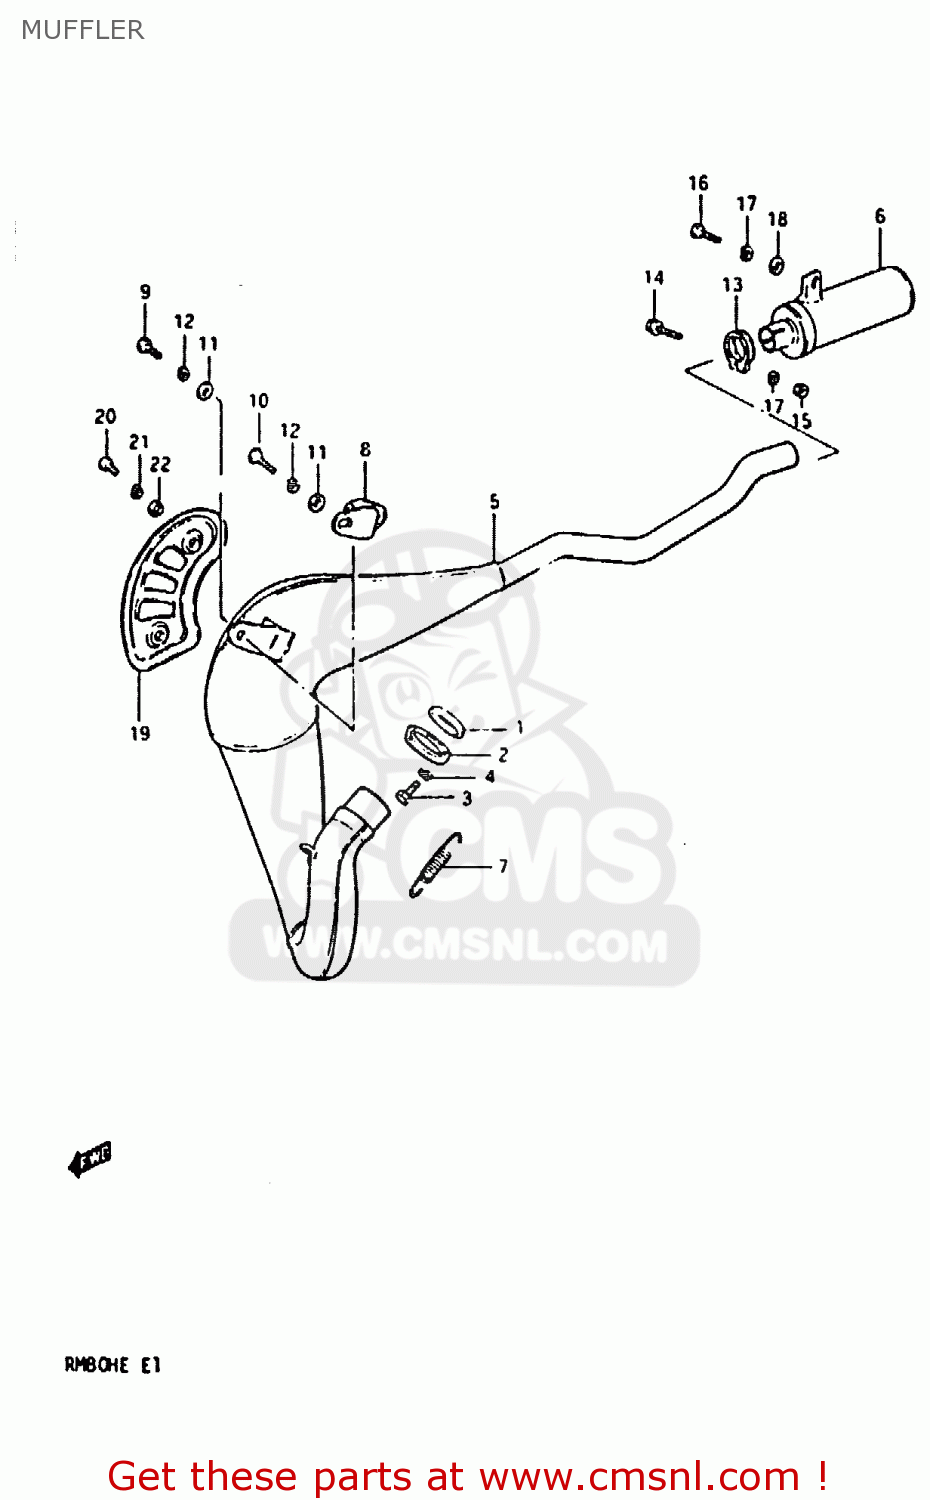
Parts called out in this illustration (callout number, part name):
1	GASKET,EXHAUST PIPE (NAS)
2	CLAMP,EXHAUST PIPE
3	BOLT 6X16
4	LOCK WASHER
5	MUFFLER, 1ST
6	MUFFLER, 2ND
7	SPRING
8	DAMPER,MUFFLER SUPPORT
9	BOLT
10	BOLT, UPPER
11	WASHER
12	LOCK WASHER
13	CLAMP,EXHAUST
14	BOLT
15	NUT 6MM
16	BOLT
17	LOCK WASHER
18	WASHER
19	COVER,MUFFLER
20	SCREW
21	LOCK WASHER
22	WASHER
